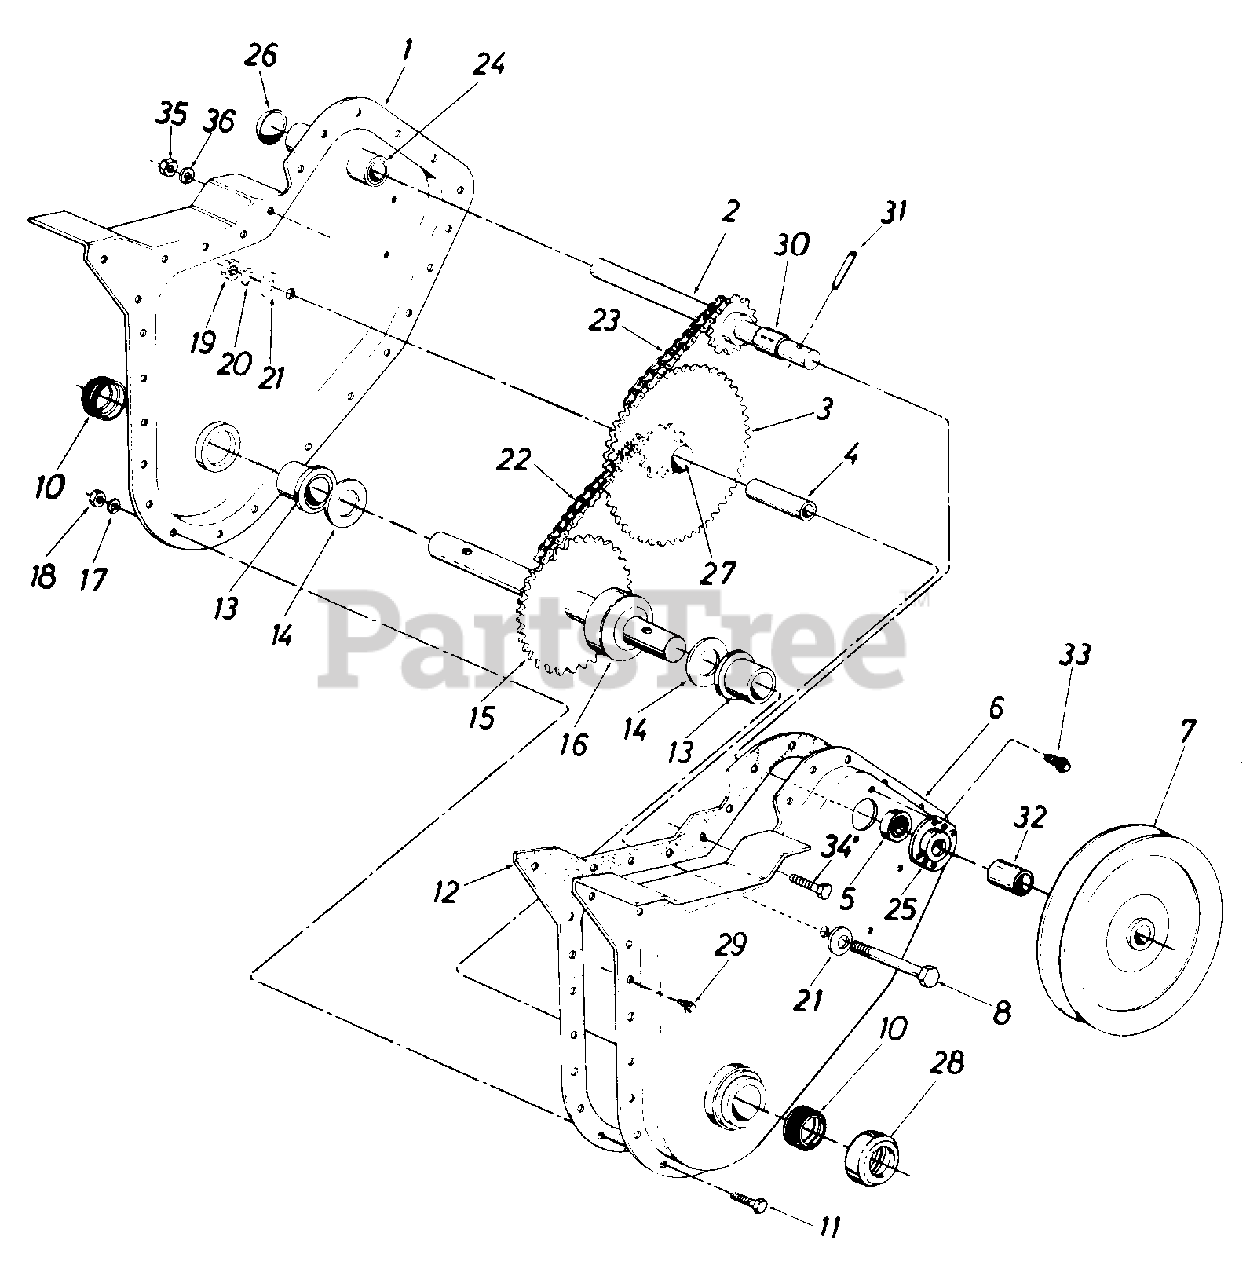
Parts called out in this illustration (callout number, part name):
1	Chain Case Ass'y.R.H.
2	Input Shaft Ass'y.
3	Hub and Sprocket Ass'y.
4	Bearing Inner Race
5	Ball Bearing
6	Chain Case Ass'y.L.H.
7	Pulley-Chain Case 51/2 x 1/2
8	Hex Bolt 3/8-24 x 2.50" Lg.
11	Hex Bolt 1/4-28 x .625" Lg.
12	Gasket
13	Flange Brg. .879 I.D.
14	Fl-Wash. .88 I.D. x 1.50 O.D. x .030
15	Tine Shaft Ass'y.
16	Spacer 7/8" I.D. x 2.0" O.D. x.68" Lg.
17	L-Wash. 1/4" Scr.
18	Hex Nut 1/4-28 Thd.
19	Hex Ins. L-Nut 3/8-24 Thd.
20	L-Wash. 3/8" I.D.
21	Bell-Wash. .406 I.D. x 1.130 O.D.
22	Chain #420-.50" Pitch x 38 Links
23	Chain #35-.375" Pitch x 50 Links
24	Bearing .62" I.D. x .813 O.D. x 1.31
25	Bearing Housing
26	Expansion Plug 13/16" Dia.
27	Bearing
28	Dust Cap
29	Hex Wash. Hd. Self-Tap Scr. 1/4-20 x .50" Lg.
30	Spacer .630 I.D. x .77 O.D. x .38" Lg.
31	Spring Pin Spiral 1/4" Dia. x 11/2 " Lg.
32	Spacer .647 x 1.25"
33	Hex Wash. Hd. Self-Tap Scr. 1/4-20 x .38" Lg.
34	Hex Bolt 5/16-18 x .75" Lg.
35	Hex Nut 5/16-18 Thd.*
36	L-Wash. 5/16" I.D.
